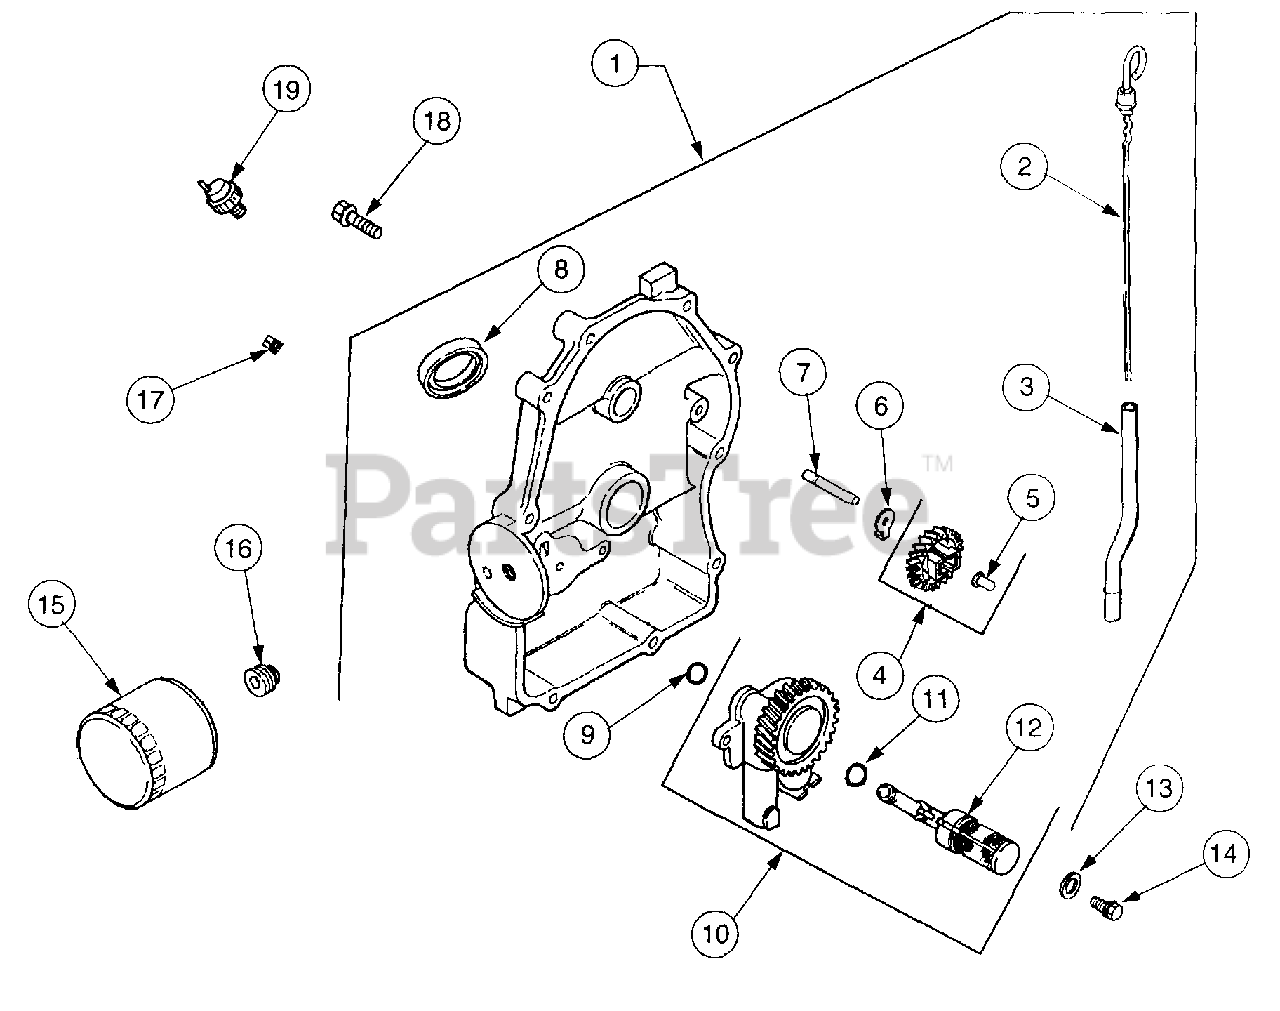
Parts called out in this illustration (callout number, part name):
1	Plate Assembly, Closure
2	Dipstick
3	Tube, Dipstick
4	Kit, Governor Gear
5	Pin, Governor Regulating
6	Tab, Locking
7	Shaft, Governor Gear
8	Seal, Oil (PTO end)
10	Oil Pump Assembly
11	O-Ring, Oil Pick-up
12	Pick-up, Oil
13	Washer, Plain
14	Screw, Hex Flange, M6 x 1.0 x 25
15	Filter, Oil
16	Nipple, Oil Filter
17	Plug, Pipe 1/8
18	Screw, Hex Flange, M8 x 1.25 x 45
19	Switch, Pressure
